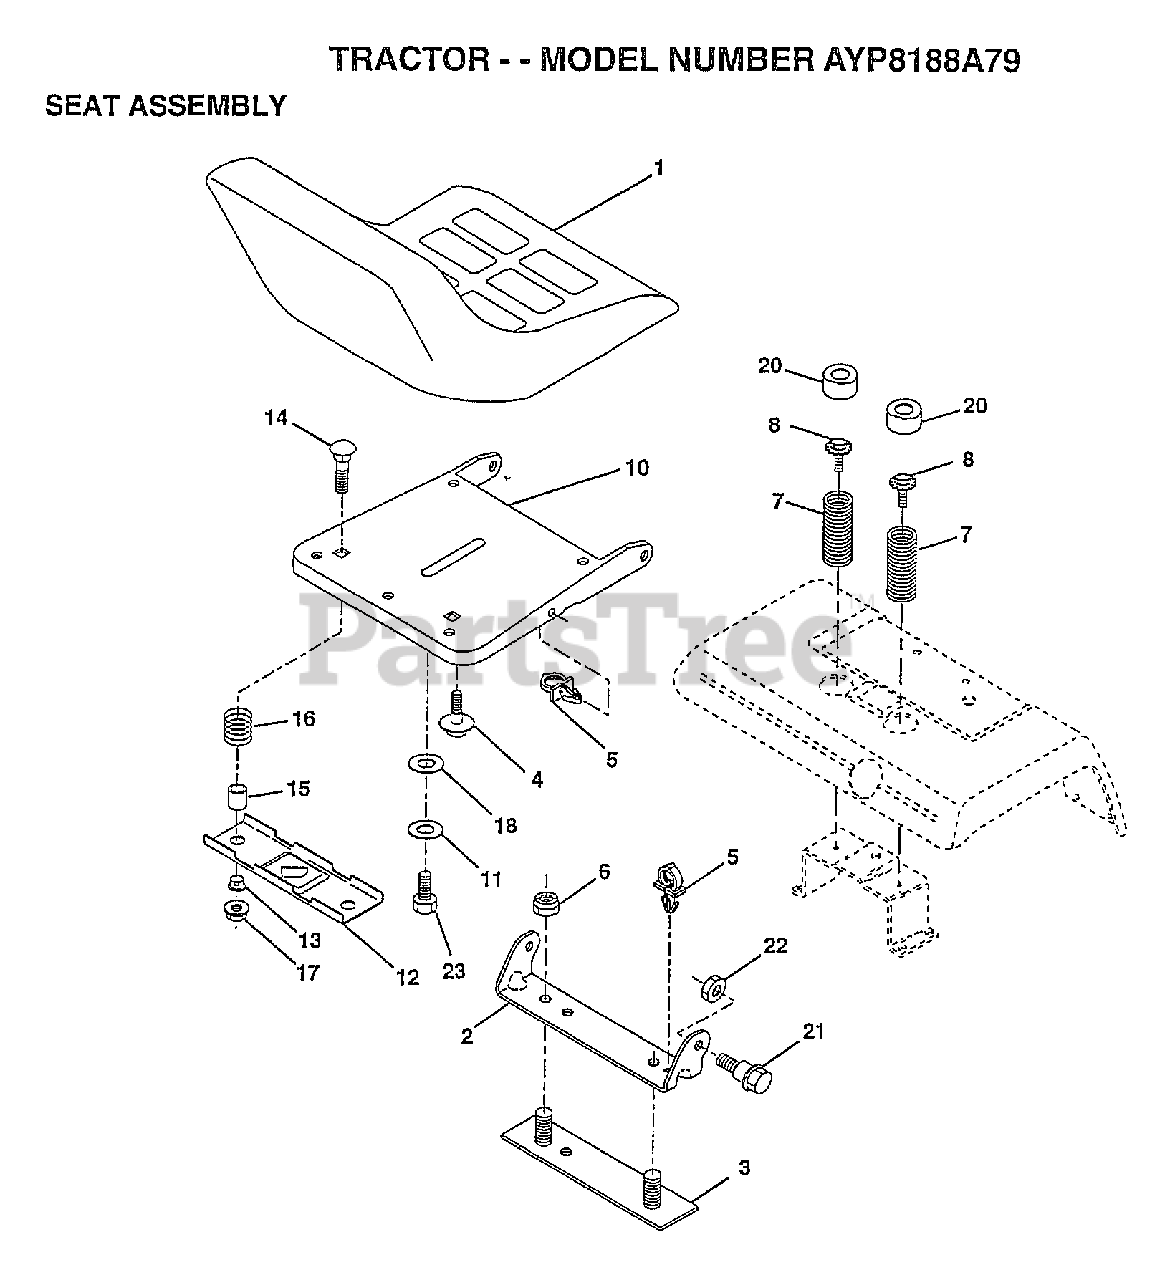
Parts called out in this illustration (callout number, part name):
1	SEAT.2400/1416.BK
2	BRACKET PVT SEAT
3	STRAP ASM FENDER
4	"BOLT,SHOULDER"
5	CLIP.PUSH-IN.HING
7	SPRING COMPRESSIO
8	BOLT.5/16-18.UNC
10	PAN-SEAT
11	LOCKWASHER
12	BRKT SWITCH
13	BUSHING
15	SPLIT SPACER
16	SPRING
18	WASHER
20	CAP SPRING
21	"BOLT,SHOULDER"
23	BOLT
